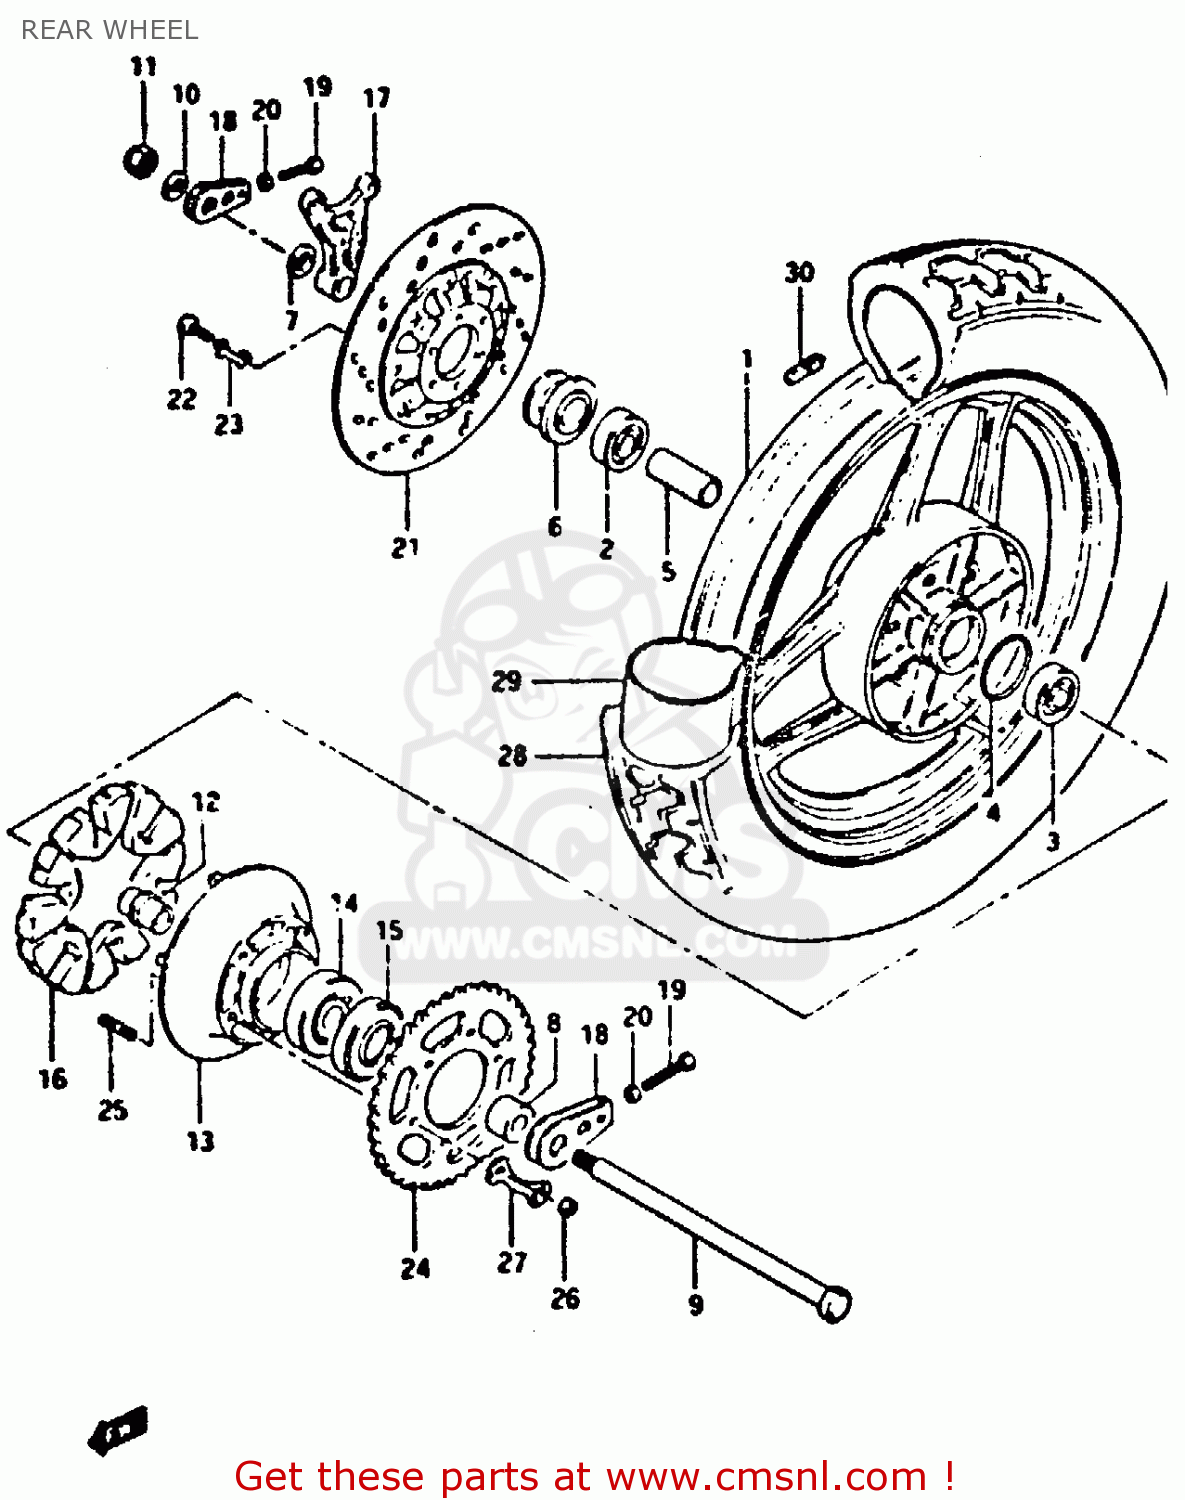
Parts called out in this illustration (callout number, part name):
1	WHEEL,REAR
2	BEARING WHEEL REAR(20X47X14)
3	BEARING, LH
4	O RING(D:2.4,ID:57.6)
5	SPACER
6	SPACER,REAR AXLE
7	SPACER
8	SPACER,REAR AXLE,LEFT
9	AXLE,REAR
10	WASHER(19X34X4)
11	NUT
12	RETAINER,REAR SPROCKET
13	DRUM,REAR SPROCKET MOUNT
14	BALL BEARING 32X75X20
15	OIL SEAL
16	CUSHION,REAR DRUM
17	BRACKET,RR,CALIPER
18	ADJUSTER,CHAIN
19	BOLT 8X50
20	NUT
21	DISC,RR BRAKE
22	BOLT
23	WASHER
24	SPROCKET, REAR (NT:38)
25	BOLT(10X35.5)
26	NUT
27	WASHER
28	TIRE
29	TUBE ASSEMBLY,WHEEL,INNER
30	BALANCER,WHEEL
